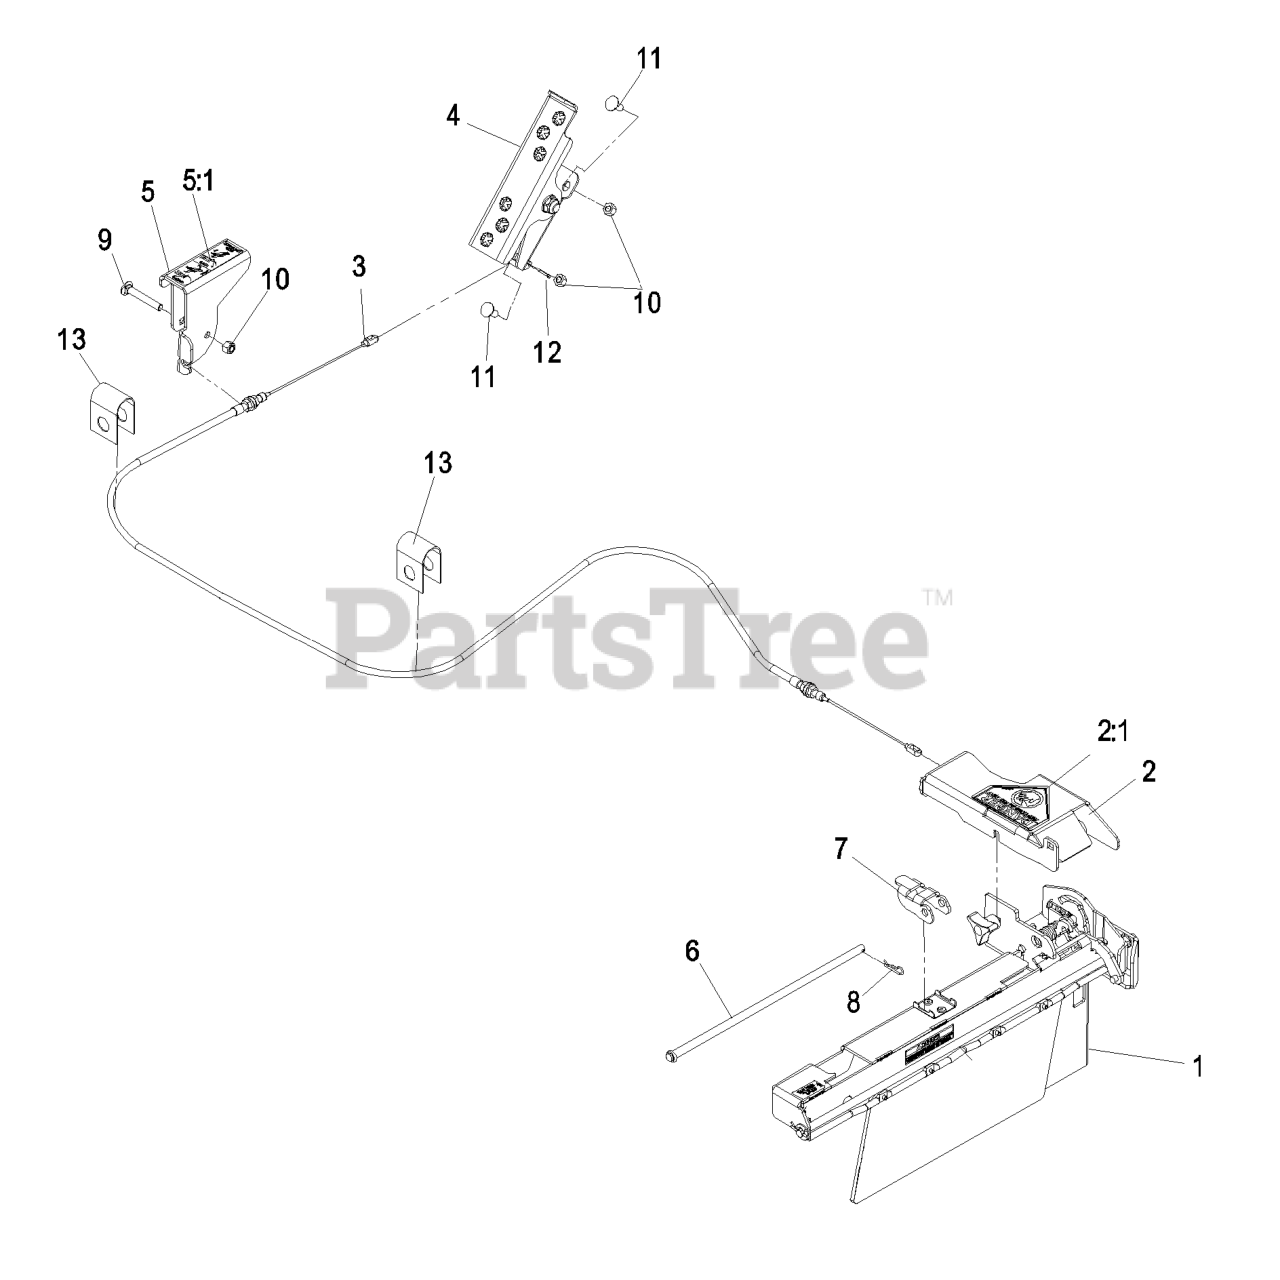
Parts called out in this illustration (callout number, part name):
1	ASM,GATE LINKAGE
2	ASM,CABLE BRACKET
2:1	DECAL-DANGER
3	CABLE,DISCHARGE GATE
4	ASM,PEDAL - OCD GATE
5	ASM,CABLE BRACKET
5:1	DECAL,OCDC OPERATION
6	ROD,CHUTE PIVOT
7	BRACKET,LINK PIVOT
8	PIN-COTTER
9	BOLT-CARR
10	NUT-LOCK, NI
11	SCREW-CARR
12	PIN-COTTER
13	STRAP,CABLE HANGER
